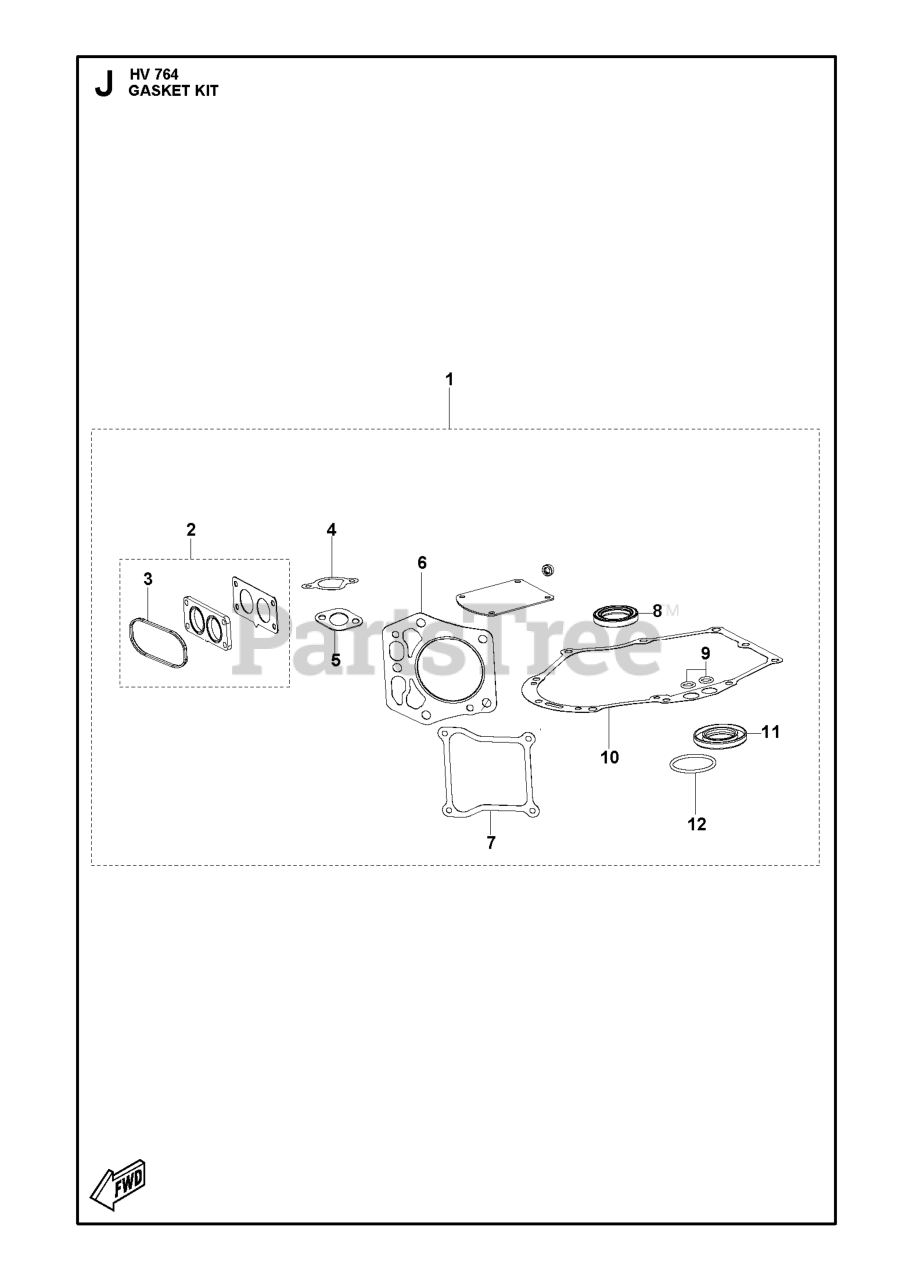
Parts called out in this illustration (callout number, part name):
5	EXHAUST GASKET
7	Husqvarna TBD
8	SEAL OIL SEAL
9	SEALING RING SEAL RING
